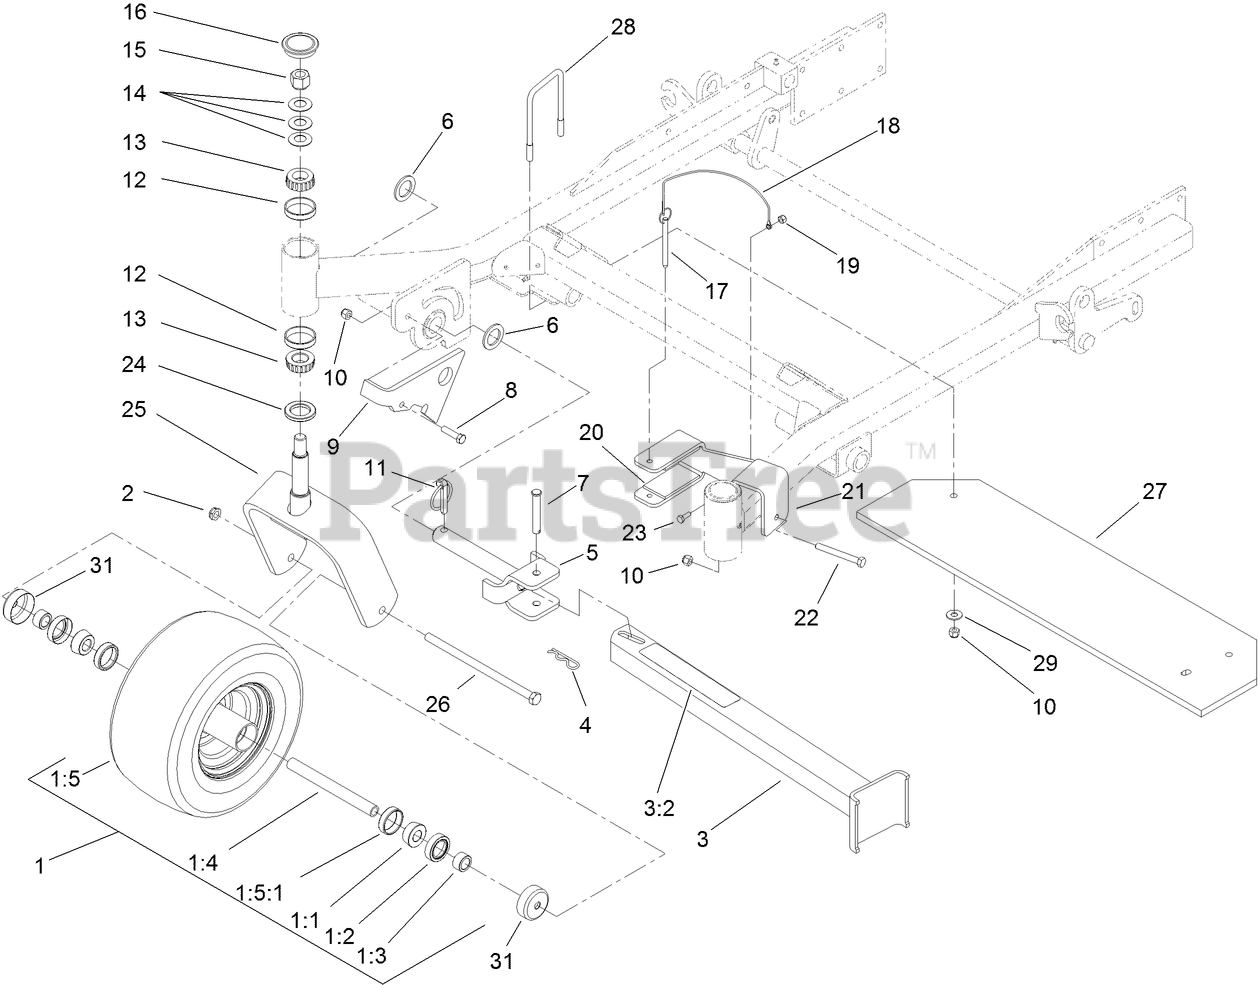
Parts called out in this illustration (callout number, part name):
1:1	BEARING-CONE, TAPER
1:2	SEAL-CASTER
1:3	SPACER-NUT
1:5:1	BEARING-CUP
2	NUT-HEX
3	LEG ASM
3:2	DECAL-Z STAND
4	PIN-HAIR
5	PIN-PIVOT
6	WASHER-THRUST
7	PIN-CLEVIS
8	SCREW-HH
10	NUT-LOCK, NI
11	PIN-LYNCH
12	BEARING-CUP, TAPERED
13	BEARING-CONE, TAPERED
14	WASHER-BELLVILLE
15	NUT-LOCK, NI
16	CAP-GREASE
17	PIN-HITCH, COTTERLESS
18	LANYARD-NYLON
19	NUT-LOCK, NI
20	CUSHION-RUBBER
21	BRACKET-CRADLE
22	SCREW-HH
23	SCREW-HH
24	SEAL-GREASE
26	SCREW-HH
27	BAR-WEIGHT
28	U-BOLT, 3IN
29	WASHER-FLAT
31	GUARD-SEAL
